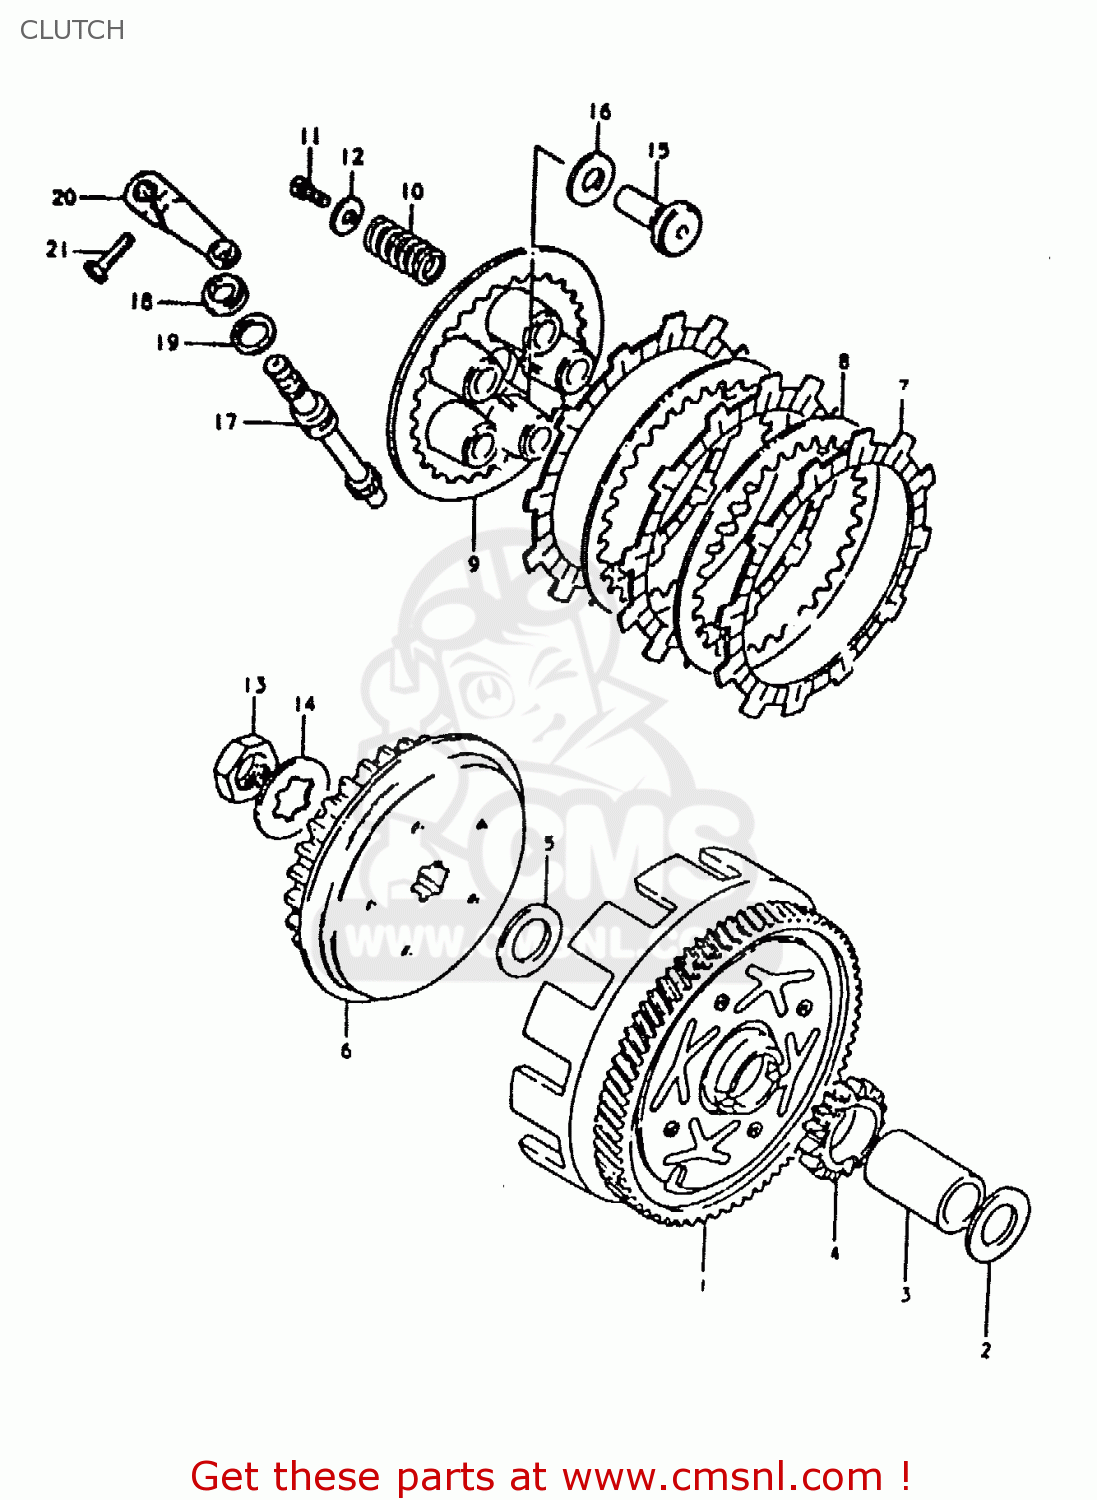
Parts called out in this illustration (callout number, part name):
1	GEAR ASSEMBLY,PRIMARY DRIVE
2	WASHER,THRUST
3	SPACER
4	GEAR,KICK STARTER DRIVE
5	WASHER
6	HUB,CLUTCH SLEEVE
7	PLATE,CLUTCH DRIVE
8	PLATE,CLUTCH DRIVEN (NAS)
9	DISC,CLUTCH PRESSURE
10	SPRING
11	BOLT(5X16)
12	WASHER (5.5X16X1.2)
13	NUT
14	WASHER,LOCK
15	RACK,CLUTCH RELEASE
16	BEARING(10X22X2.8)
17	PINION,CLUTCH RELEASE
18	OIL SEAL
19	WASHER (12X17X1)
20	ARM,CLUTCH RELEASE
21	BOLT, UPPER
